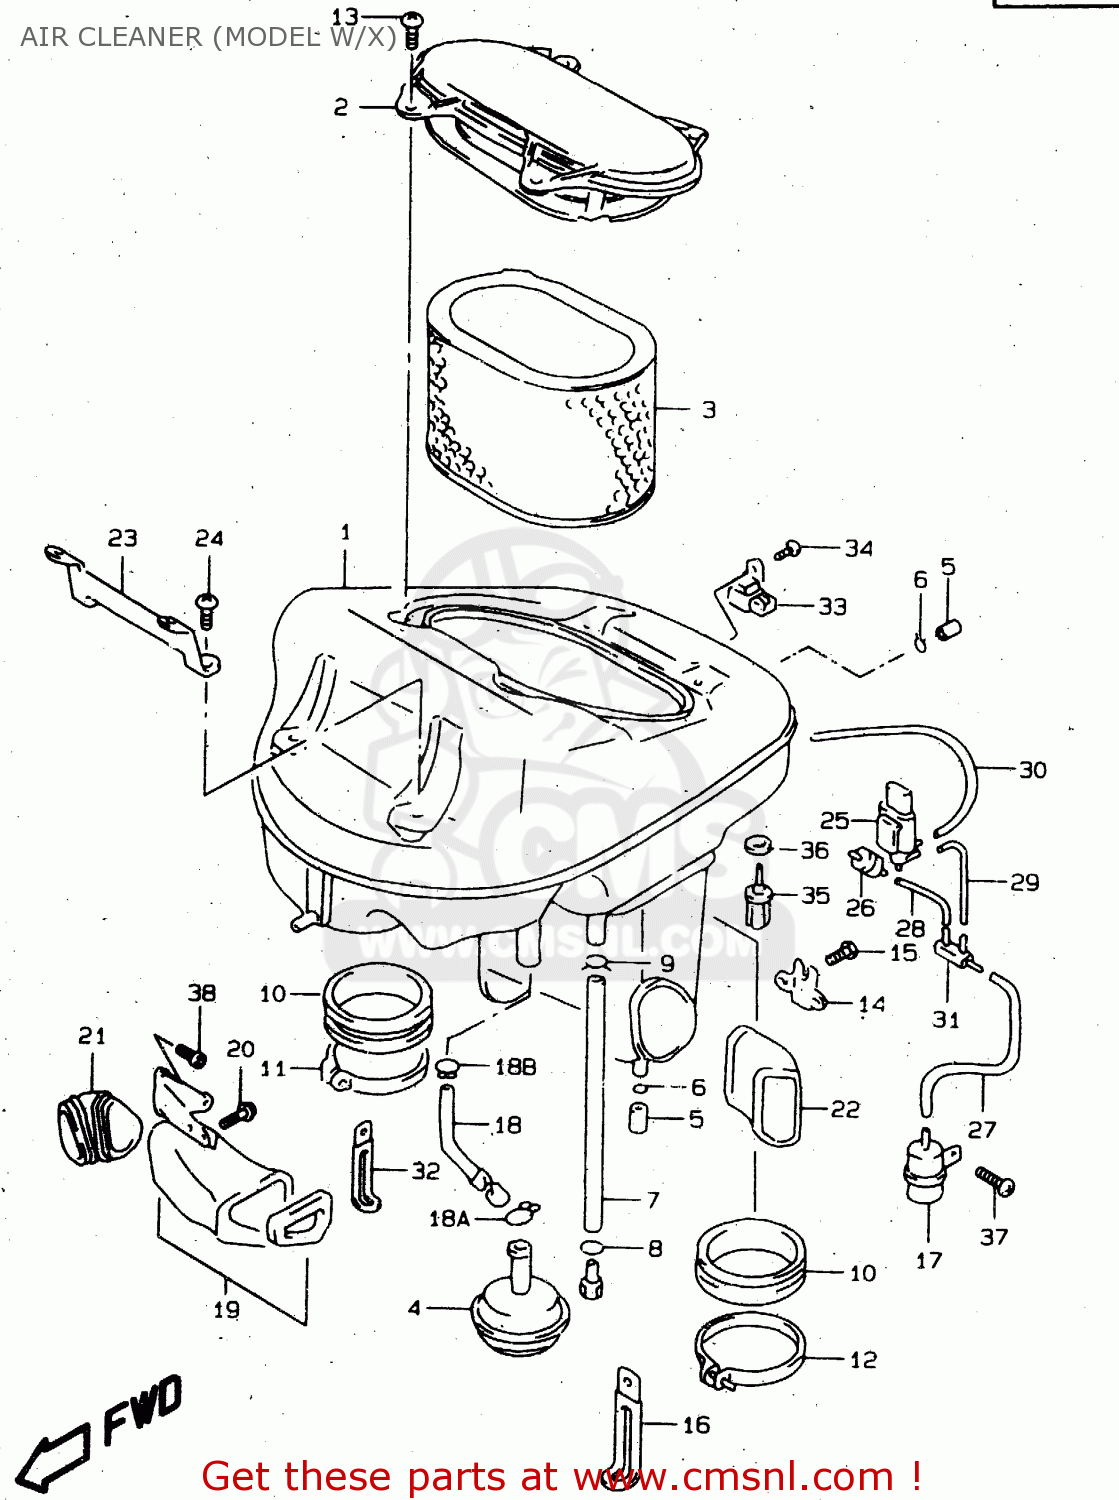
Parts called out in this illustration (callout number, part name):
1	CLEANER ASSY,AIR
2	CAP,AIR CLEANER
3	FILTER,AIR CLEANER
4	DIAPHRAGM,CONT VALVE
5	PLUG
6	CLIP
7	TUBE,DRAIN
8	CLIP
9	CLIP
10	TUBE,OUTLET
11	CLAMP
12	CLAMP
13	SCREW 5X12
14	BRACKET,SOLENOID VALVE
15	SCREW
16	CLAMP(L:65)
17	CHAMBER,VACUUM
18	TUBE,BREATHER
18A	CLIP
18B	CLIP
19	DUCT,AIR CLEANER
20	BOLT
21	BOOT,AIR INLET,R
22	BOOT,AIR INLET,L
23	BRACKET,AIR CLEANER
24	SCREW 6X12
25	VALVE ASSY,3WAY SOLENOID
26	VALVE,CHECK
27	HOSE(4X8X600)
28	HOSE(4X8X600)
29	HOSE(4X8X600)
30	HOSE(4X8X600)
31	JOINT
32	CLAMP(L:80)
33	SENSOR,BOOST
34	SCREW
35	SENSOR,WATER TEMP
36	GASKET(12.2X21X0.8) (NAS)
37	SCREW 5X12
38	BOLT
